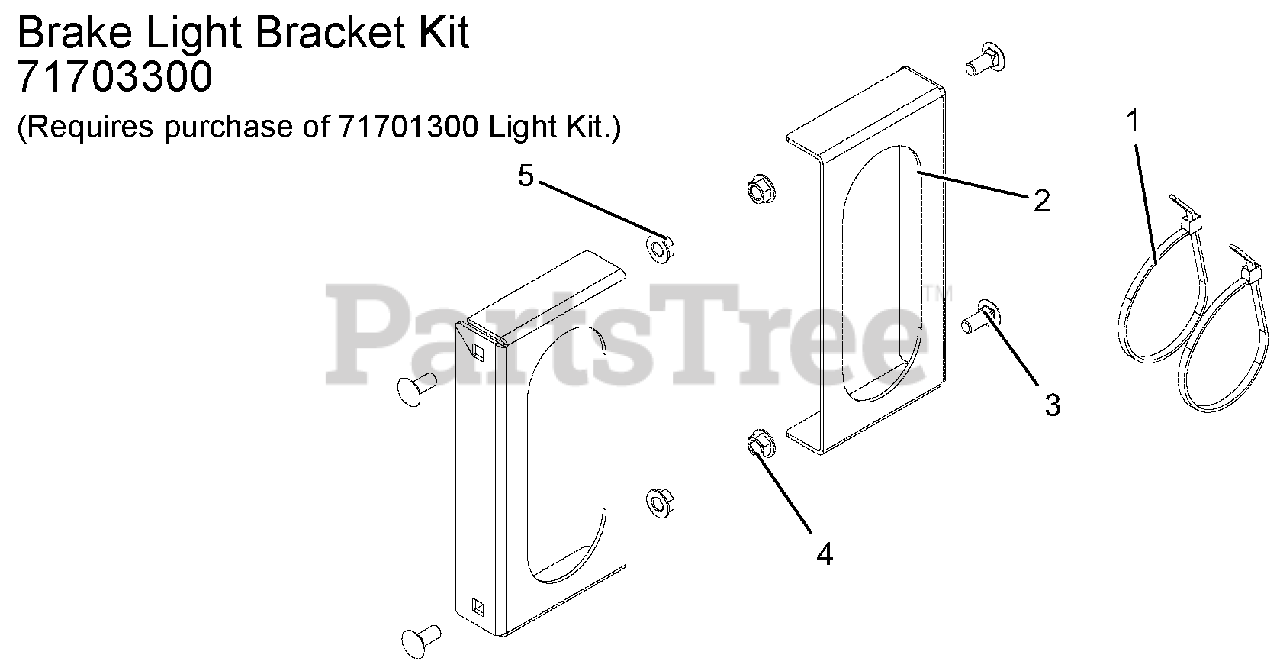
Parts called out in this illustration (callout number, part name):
1	TIE WRAP
2	MOUNT, TAILIGHT
3	@BLT-RDHDSQNK .31-18X.75 G5YZ
4	@NUT-LK-TOP-FLG .31-18 YWZC
5	@NUT-LK-TOP-FLG .31-18 YWZC
